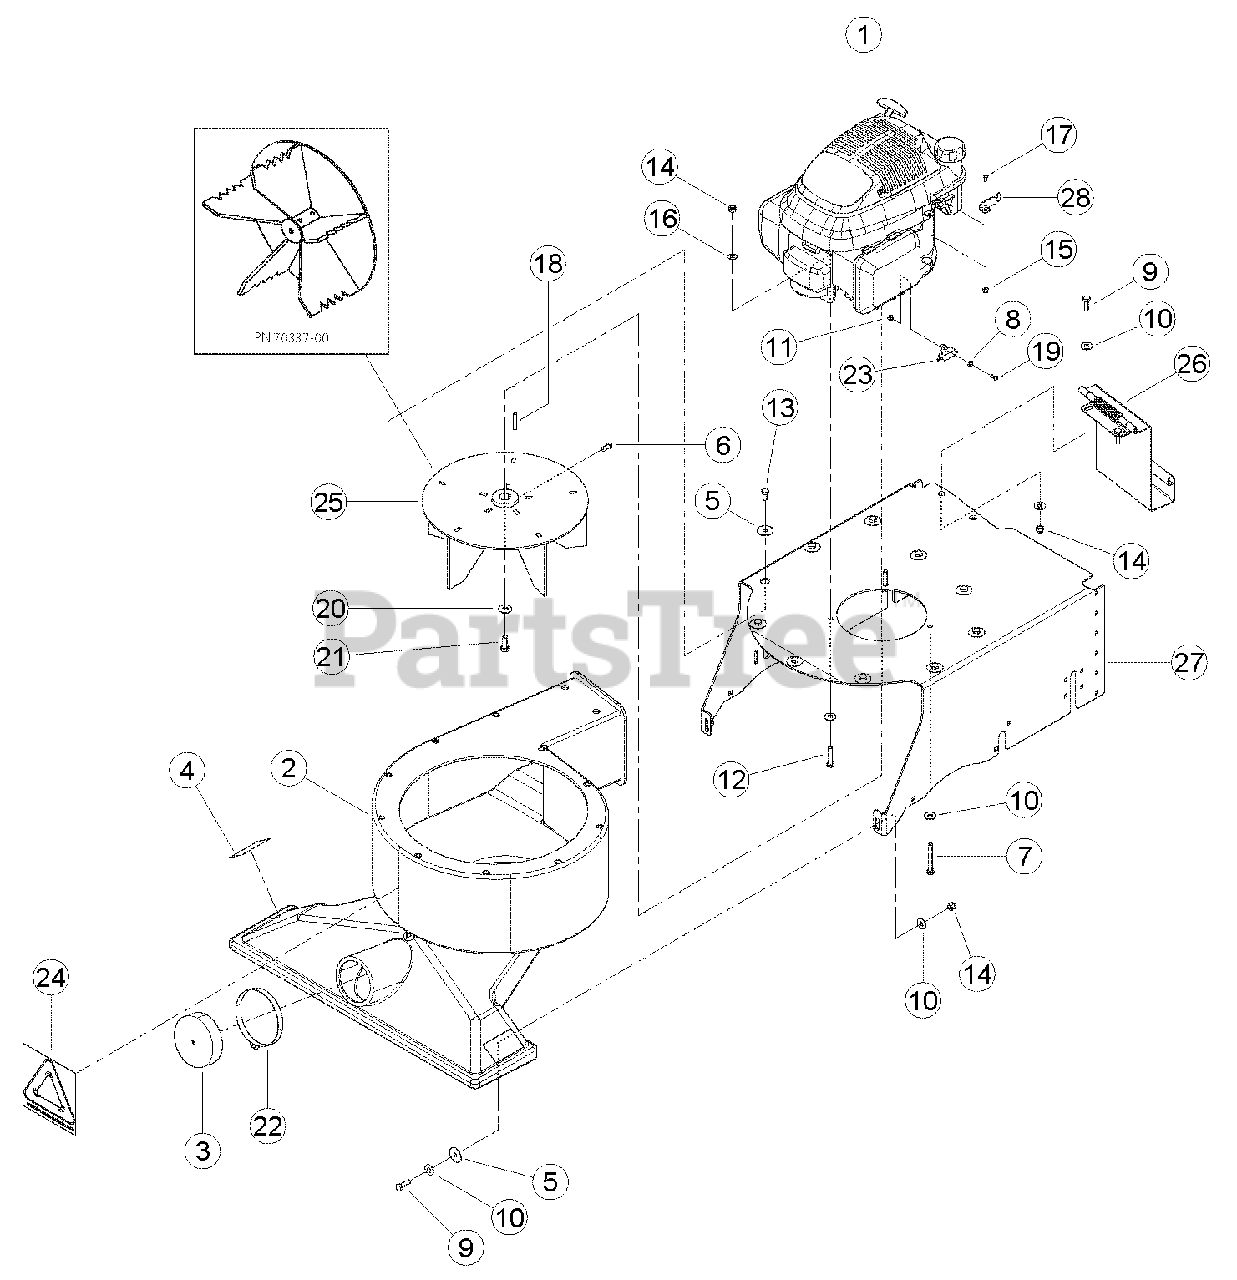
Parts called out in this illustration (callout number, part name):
1	ENGINE, 5.5 HP HONDA GCV (FOR SERVICE SEE ENGINE OWNER"S MANUAL OR YOUR NEAREST AUTHORIZED HONDA ENGINE DEALER)
2	HOUSING, FAN W/INTAKE
3	CAP, ROUND VINYL (4 X 1)
4	DECAL, DANGER
5	WASHER, 5/16 FENDER ZP
6	SCREW, 5/16-18 X 5/8 SQ HD SET
7	BOLT, 5/16 X 2-1/2 HEX HD GR5 ZP
9	BOLT, 5/16 X 1 HHCS GR5 ZP
10	WASHER, 5/16 FLAT ZP
12	BOLT, 5/16 X 1-1/2 HEX HD GR5 ZP
13	BOLT, 5/16 X 5/8 HEX HD GR5 ZP
14	NUT, 5/16 NE NYLOCK ZP
16	WASHER, 5/16 SAE FLAT ZP
18	KEY, 3/16 SQUARE X 1-1/4 LONG PLAIN
20	WASHER, 3/8 GR8 USS ZP
21	BOLT, 3/8 X 1 HHCS GR5 NF ZP
22	CLAMP, 4 IN. HOSE
24	DECAL, COLLECT IT
26	ASSEMBLY, EXHAUST DOOR
27	SUPPORT, BEARVAC FRAME
